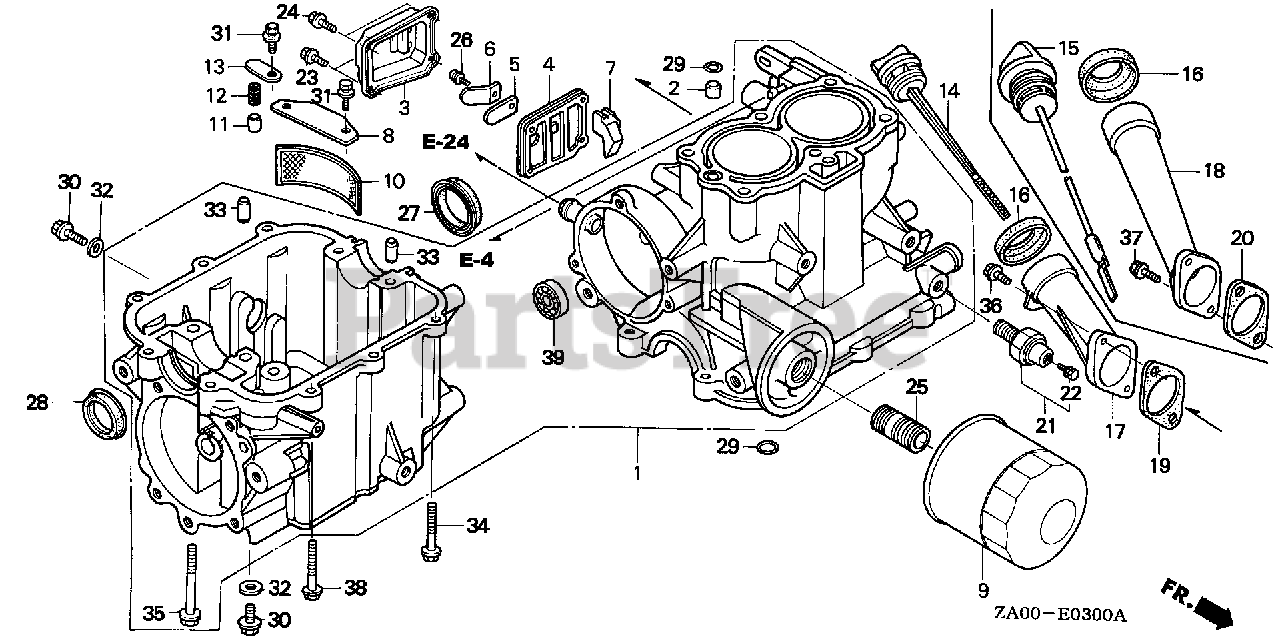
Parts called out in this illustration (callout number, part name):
1	CYLINDER ASSY.
2	ORIFICE, OIL CONTROL
3	COVER, BREATHER
4	PLATE, BREATHER
5	PLATE, VALVE
6	STOPPER, VALVE
7	GUARD, BREATHER
8	PLATE, OIL FILTER
9	FILTER, OIL (TOYO ROKI)
9	FILTER, OIL (TOKYO ROKI)
10	SCREEN, OIL FILTER
11	VALVE, CHECK
12	SPRING, CHECK VALVE
13	PLATE, CHECK VALVE
14	CAP, OIL FILLER
16	GASKET, OIL FILLER CAP
17	PIPE, OIL FILLER
19	GASKET, OIL PIPE
21	SWITCH, OIL PRESSURE
22	BOLT-WASHER (4X8) (DENSO)
23	BOLT, FLANGE (6X12) (CT200)
23	BOLT, FLANGE (6X14) (CT200)
24	BOLT, FLANGE (6X14) (CT200)
25	HOLDER, OIL FILTER
26	SCREW-WASHER (5X8)
27	OIL SEAL (33X48X7)
28	OIL SEAL (30X44X7)
29	O-RING (10.8X2.4) (ARAI)
30	BOLT, DRAIN PLUG (12MM)
31	BOLT-WASHER (6X12)
32	WASHER, DRAIN PLUG (12MM)
33	PIN, DOWEL (10X16)
34	BOLT, FLANGE (6X28)
35	BOLT, FLANGE (8X55)
36	BOLT, FLANGE (6X16)
38	BOLT, FLANGE (6X32)
39	BEARING, RADIAL BALL (6202)
